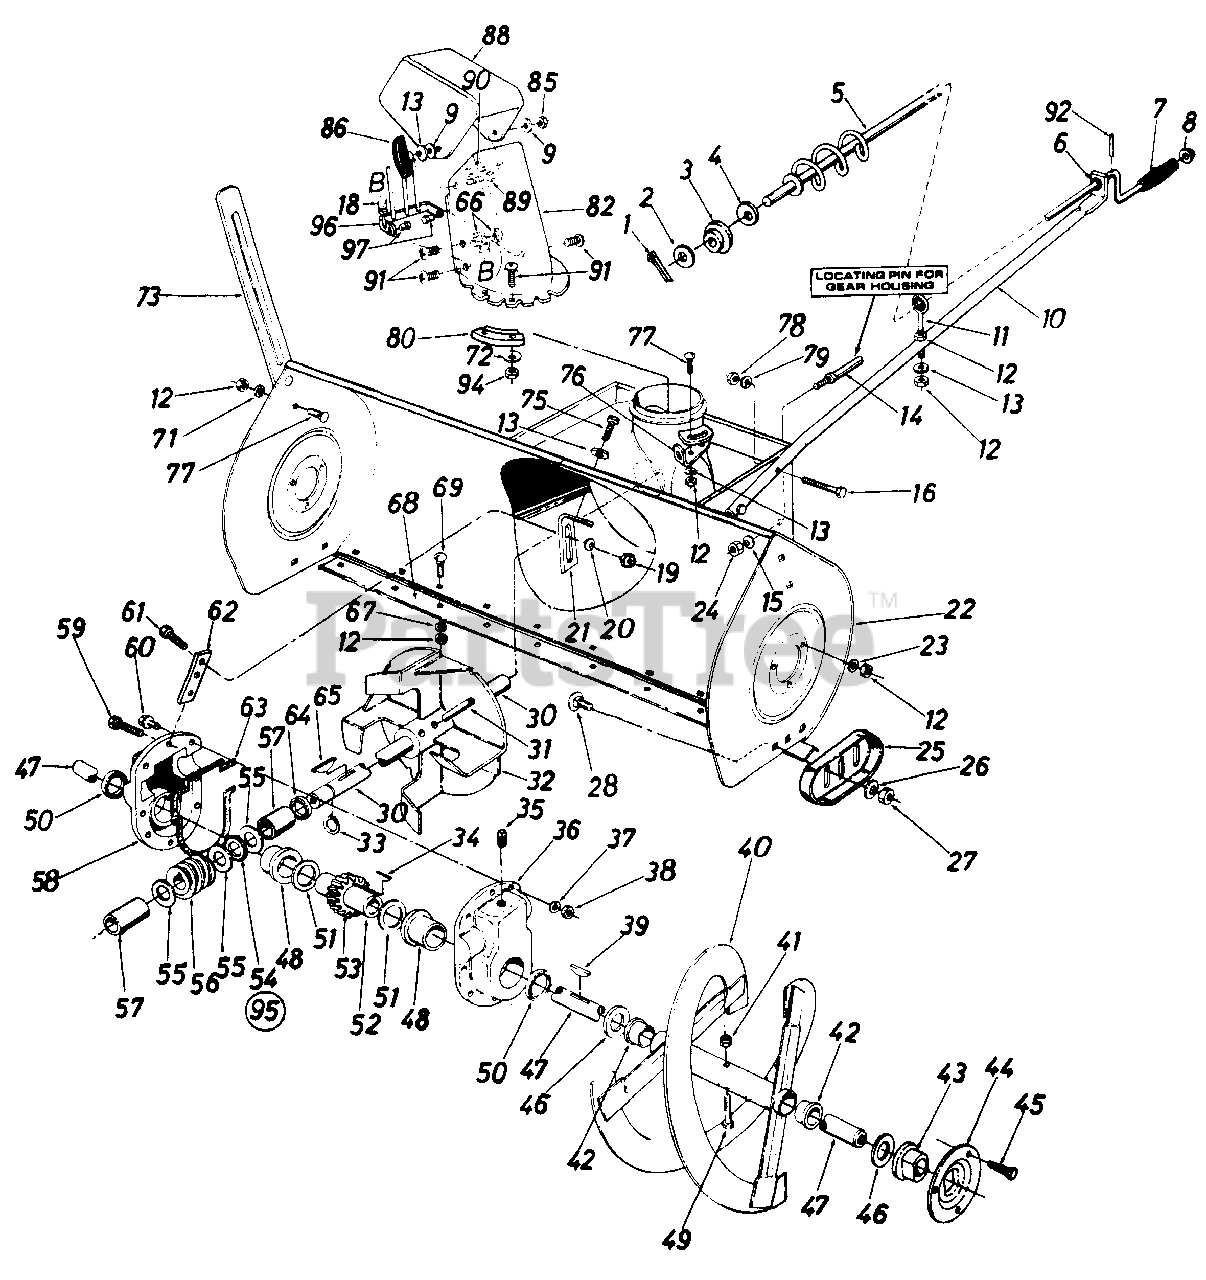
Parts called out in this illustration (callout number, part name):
1	Cotter Pin
2	Fl.-Wash. .39" I.D. x .62" O.D.
3	Plastic Bushing
4	Fl.-Wash. .385" I.D. x .62" O.D.
5	Chute Crank Ass'y.
6	Plastic Bushing
7	Knob (Black)
8	Push Nut 3/8" Rod
9	Fl.-Wash. .344" I.D. x 1.25" O.D.
10	Chute Crank Support Tubing
11	Eyebolt
12	Hex Nut 5/16-18 Thd.*
13	Bell.-Wash. .345" I.D. x .88" O.D.
14	Stud 3/8-16 x 2.75" Lg.
15	Bell.-Wash. .400" I.D. x .88" O.D.
16	Hex Bolt 3/8-24 x 1.25" 4.*
18	Extension Spring
19	Hex Nut 1/4-28 Thd.
20	Bell.-Wash. .265" I.D. x .75" O.D.
22	45" Snow Blower Housing Ass'y.
23	L.-Wash. 5/16" I.D.*
24	Hex Jam Nut 3/8-16 Thd.
25	Slide Shoe
26	Bell.-Wash. .400" I.D. x .88" O.D.
27	Hex Jam Nut 3/8-16 Thd.
28	Carriage Bolt 3/8-16 x .62" 4.*
30	Blower Axle .875" Dia. x 14.75" 4
31	Spring Pin Spir. 5/16" Dia. x 1.75" 4.
34	#91 Woodr-Key 1/4 x 3/4" Dia. (HDN)
35	Vent Plug
36	Gear Hsg. Half L.H.
37	Spr.-Wash. .32" I.D. x .62" O.D.
38	Hex Ins. L.-Nut 5/16-18 Thd.
39	#91 Woodr-Key 1/4 x 3/4" Dia. (HDN)
41	Hex Ins. L.-Nut 5/16-18 Thd.
42	Plastic Bushing
43	Flange Brg. w/flats l" I.D.
44	Bearing Housing
45	Hex Sems Bolt 5/16-18 x .75" Lg.
46	Fl.-Wash. 1.00" I.D. x 1.75" O.D.
47	Spiral Axle
48	Flange Bearing 1.503" I.D.
49	Shear Bolt 5/16-18 x 1.75" Lg.
50	Oil Seal 1.50" I.D.
51	Fl.-Wash. 1.50" I.D. x 2.00" O.D.
52	Worm Gear Shaft
53	Double Threaded Worm Gear- L.H.
54	Thrust Brg. - .88" I.D. x 1.44" O.D.
55	Fl.-Wash. .88" 1 .D. x 1.4" O.D.
56	Double Threaded Worm-L.H.
57	Sleeve
58	Gear Hsg. Half - R.H.
59	Hex Bolt 5/16-18 x 1.25" Lg.*
60	Hex Bolt 5/16-18 x 1.0" Lg. (Grade 5)
61	Hex Bolt 1/4-28 x .75" Lg.
62	Gear Housing Support Plate
63	Rubber Gasket
64	Oil Seal - .875" I.D.
65	#9 Hi-Pro Key 3/16 x 3/4" Dia. (HT.)
66	Hex L-Nut 1/4-20 Thd.
67	L.-Wash. 5/16" I.D.*
69	Carriage Bolt 5/16-18 x 1.00" Lg.
71	L-Wash. 5/16" I.D.*
72	Fl.-Wash. 1/4" I.D.
73	Guide Blade
75	Hex Wash. Hd. AB Tap Scr. 5/16" x .75" Lg.
77	Carriage Bolt 5/16-18 x .75" Lg.
78	Hex Ins. L.-Nut 3/8-24 Thd.
79	L.-Wash. 3/8" I.D.*
80	Chute Flange Keeper
82	Lower Chute 0 0 N
85	Hex Cent. L.-Nut 5/16-18 Thd.
86	Knob Handle
88	Upper Chute N
89	Carriage Bolt 5/16-18 x 1.00" Lg.
90	Truss Mach. Scr. 5/16-18 x .75" Lg.
91	Truss Mach. Scr. 1/4-20 x .75"
92	Roll Pin .12" Dia. x .63"
94	Hex Cent. L-Nut 1/4-20 Thd.
95	Gear Box Ass'y.-Comp.N
97	Shld. Nut 1/4-20 Thd.
